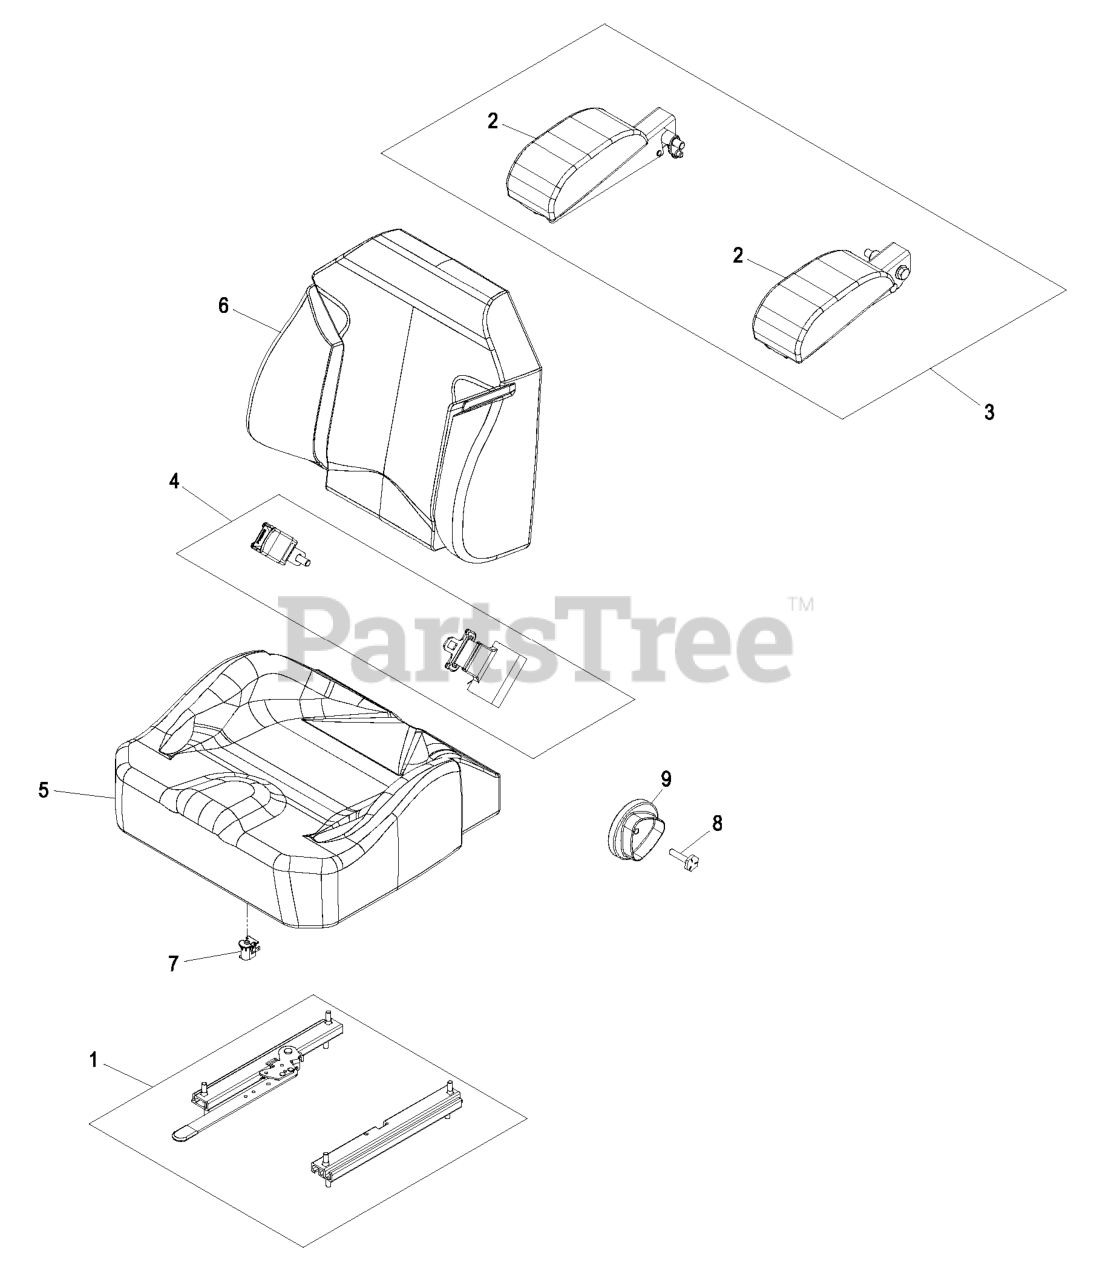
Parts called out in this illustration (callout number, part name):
1	SEAT TRACK SET
2	SET,ARM REST PADS
3	KIT,ARM REST SET
4	SEAT BELT KIT (SHORT)
5	COVER,CUSHION
6	COVER,BACK
7	SWITCH-BAIL
8	SCREW-SHOULDER,HH
9	KNOB-CIRCULAR
